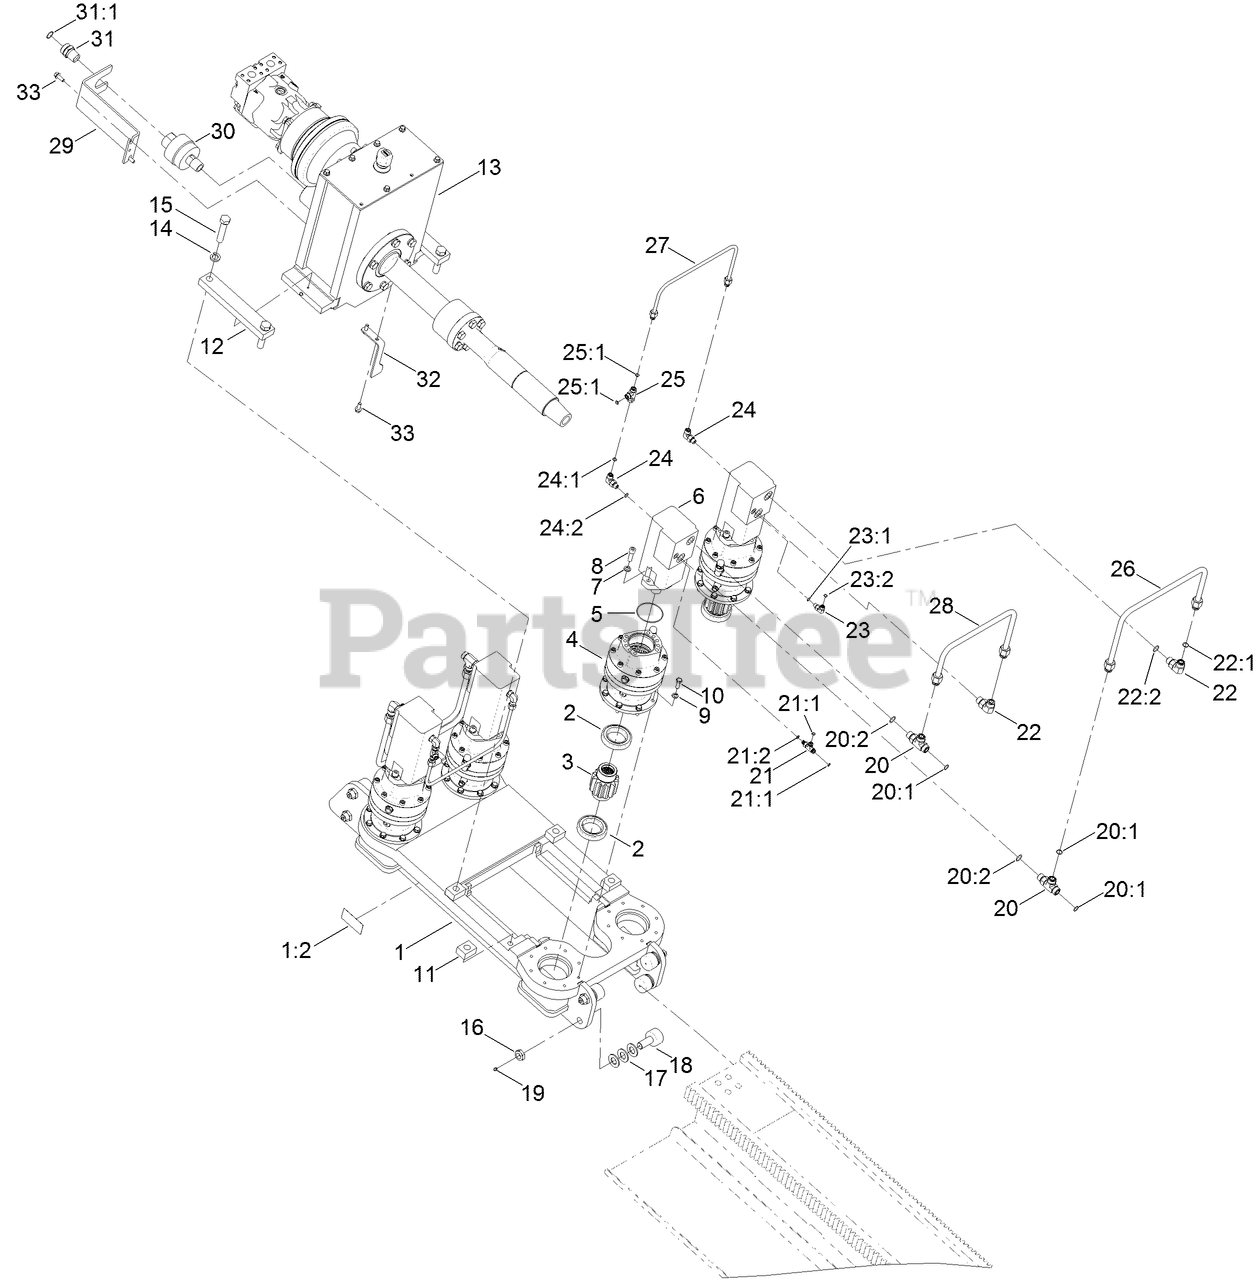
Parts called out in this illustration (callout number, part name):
1	CARRIAGE ASM
1:2	DECAL-DANGER, CRUSHING
2	BEARING-BALL, RADIAL
3	PINION-DRIVE, CARRIAGE
4	PLANETARY GEARBOX ASM
6	HYD MOTOR ASM
7	WASHER-LOCK
8	SCREW-HSH
9	WASHER-LOCK
10	SCREW-HH
11	SPACER-CLAMP, CARRIAGE
12	CLAMP-ROTARY BOX, CARRIAGE
13	ROTARY BOX ASM
14	WASHER-LOCK
15	SCREW-HH
16	NUT-LOCK, NI
18	BEARING-FOLLOWER, CAM
19	FITTING-GREASE, ZERK
20	FITTING-TEE
20:1	O-RING
20:2	O-RING
21	FITTING-TEE
21:1	O-RING
21:2	O-RING
22	FITTING-ELBOW-90
22:1	O-RING
22:2	O-RING
23	FITTING-90 DEG
23:1	O-RING
23:2	O-RING
24	FITTING-ELBOW, 90 DEG
24:1	O-RING
24:2	O-RING
25	FITTING-TEE, SWIVEL NUT
25:1	O-RING
26	TUBE-HYD, 5/8 IN (MOTOR TO MOTOR)
27	TUBE-HYD, 3/8 IN (CASE DRAIN MTR TO MTR)
28	TUBE-HYD, 5/8 IN (MOTOR TO MOTOR)
29	BRACKET-SWIVEL, MUD
30	SWIVEL-MUD
31	FITTING-STRAIGHT
31:1	O-RING
32	PLATE-TRIGGER, PROXIMITY
33	SCREW-HHF
